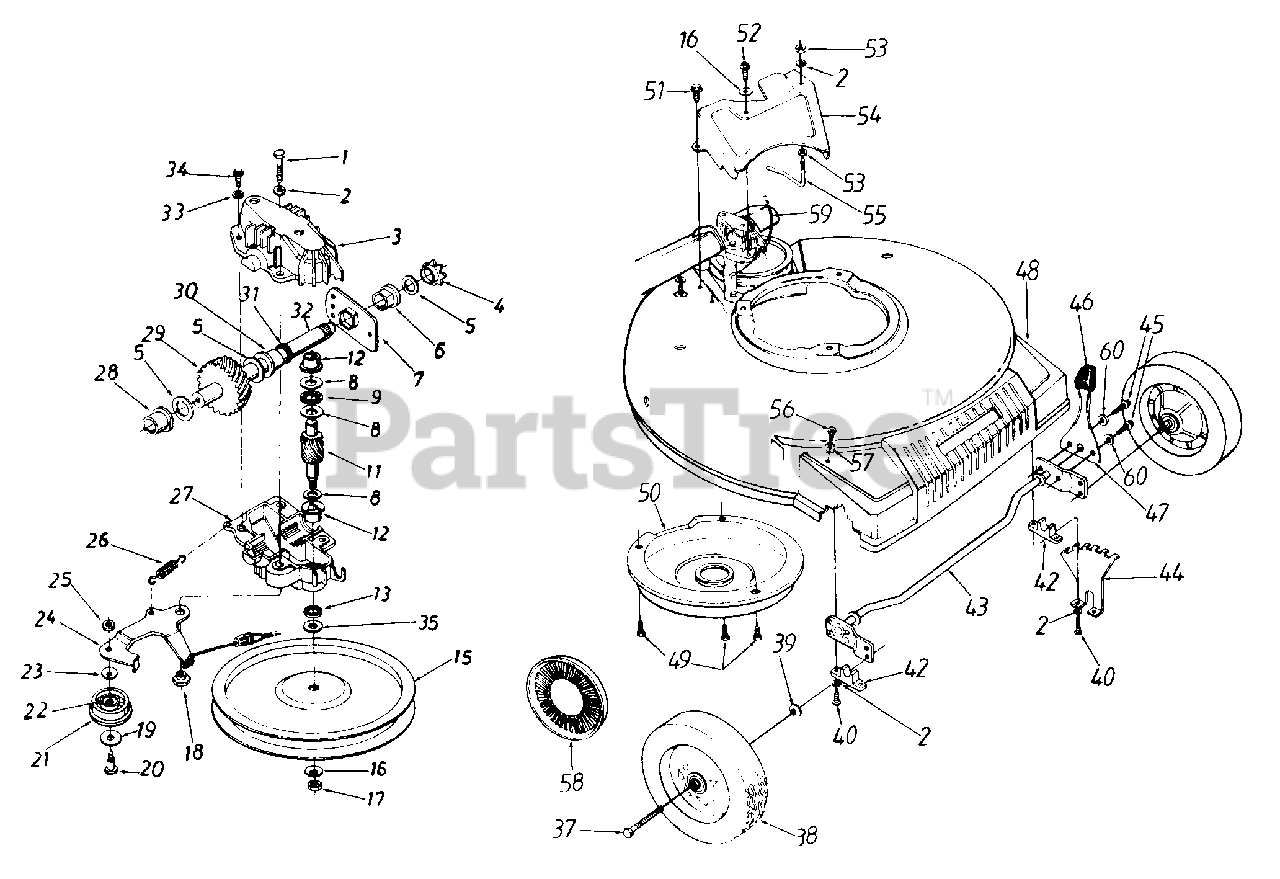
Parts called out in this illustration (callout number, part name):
1	Hex Patch Bolt 1/4-20 x 1.25"
2	L-Wash. 1/4" I.D.
3	Upper Hsg. Half
4	#48 Sprocket 7 T x 1/2 Pitch
5	Fl-Wash. 518" I.D. x .030
6	Hex Flange Brg. .631" I.D.
8	Thrust Wash. .382" I.D. x .70" O.D.
9	Thrust Bearing .375" I.D. x .812" O.D.
11	11 Tooth Pinion Shaft
12	Flange Bearing
13	Oil Seal
15	Fl-Pulley 5.06" O.D.
16	Bell-Wash. .265" I.D. x .75"
17	Hex L-Nut 1/4-28 L.H. Thd.
18	Shld. Spacer .375" Dia. x .170
19	Fl-Wash. .390" I.D. x 1.0"
20	Shld. Bolt .375" Dia. x .40"
21	Fl-Idler Plastic 1.50" Dia.
22	Needle Brg. .375" x .31
24	Idler Brk't. Ass'y.
25	Hex Patch L-Nut 1/4-28 Thd.
26	Extension Spring 1.12" Lg.
27	Lower Hsg. Half
28	Flange Bearing .566 Dia.
29	33 Tooth Helical Gear
30	Flange Bearing .629 Dia
31	Oil Seal .625 Dia.
32	Gear Sprocket Shaft
33	L-Wash. #10 I D
34	Hex B-Tap Scr. #10 x .62"
35	Hex Washer .26" x .88"
37	Front Axle Bolt
38	Wheel Ass'y. Comp. 8 x 2"
39	Bell-Wash. .380n I.D. x .88
40	Hex B-Tap Scr. 1/4-20
42	Block Bushing
45	Hex TT-Tap Scr. 1/4-20 x .38"
46	Knob
47	Spring Lever
48	Plastic Front End
49	Hex B-Tap Scr. 1/4" x .38"
52	Hex Wash. Hd. B-Tap Scr. 1/4 x .62"
53	Hex Nut 1/4-20 Thd.
56	Truss B-Tap Scr. 5/16 x .75"
57	Bell-Wash. .345" I.D. x .88"
58	Hub Cap
59	S.P. Cable 44" Lg.
60	External L-Wash. 114" I.D.
